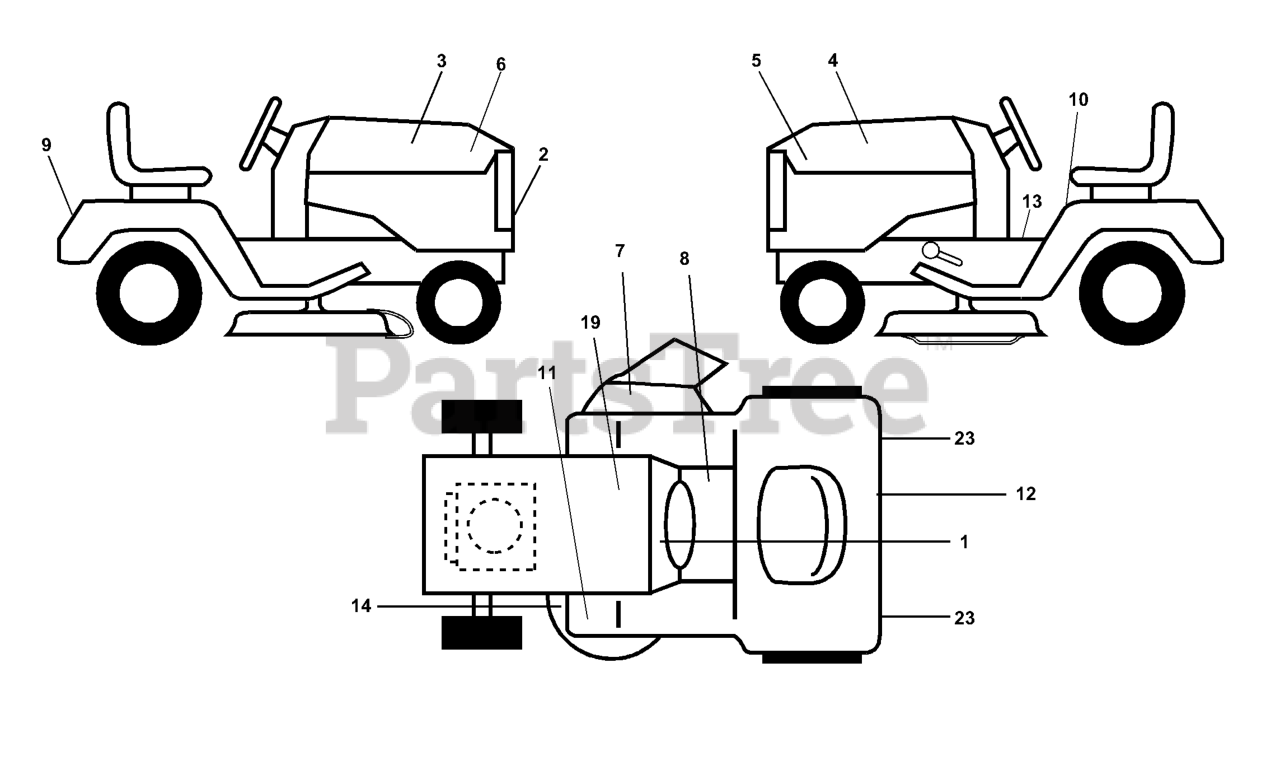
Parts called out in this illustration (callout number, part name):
2	DECAL GRILL HUSQ NLA
3	DECAL-HOOD R.H.
4	DECAL-HOOD L.H.
5	DECAL HOOD LH
6	DECAL HOOD RH
7	DECAL WARNING (ENGLISH/FRENCH)
8	DECAL PARK BRAKE
9	DECAL FENDER NLA
10	DECAL CAUTION
12	DECAL D-BAR
19	DECAL BTRY SYMBOLS
23	REFLECTOR-TAIL YT
